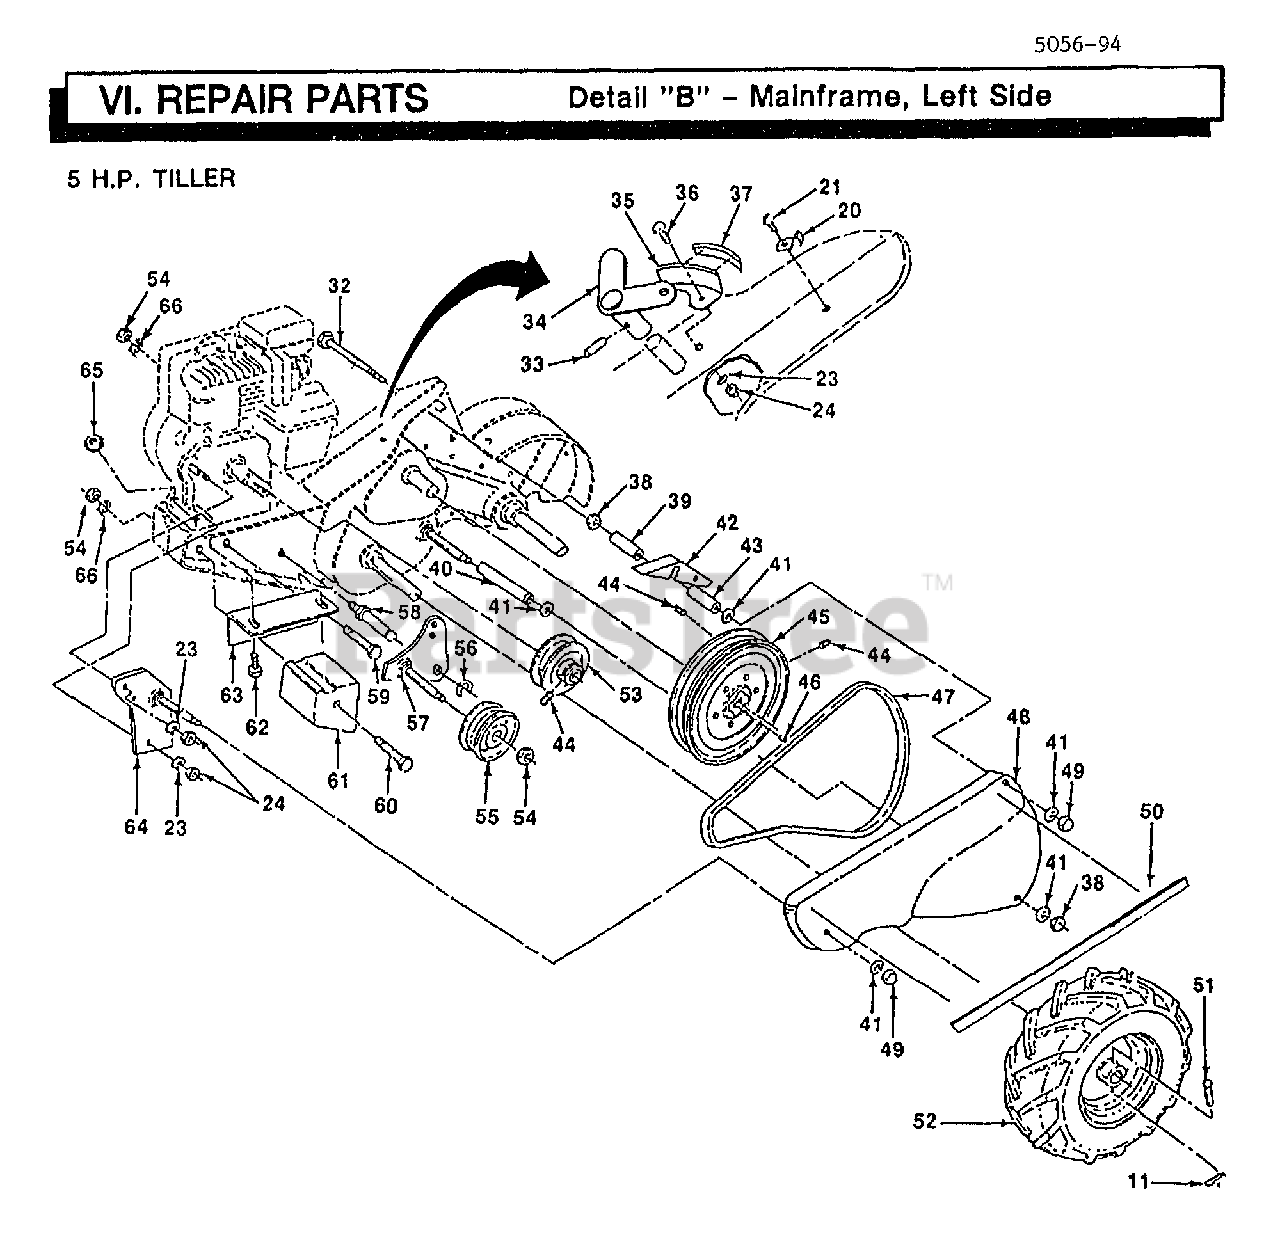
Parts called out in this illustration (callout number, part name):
11	RETAINER M
23	LOCKWASHER
32	BOLT-HEX TI
34	LEVER ASM CRT
35	PANEL TI
36	BOLT
38	NUT.HEX.5/16-18
39	SPACER CRT
40	SPACER
41	WASHER
42	GUARD CRT
43	SPACER CRT
44	SET SCREW
45	"SHEAVE 10"" CRT"
46	KEY T
49	NUT TI
50	DECAL BELT GUARD
52A	TIRE.CHV.13X5.0-6
54	NUT.HEX.3/8-16UNC
55	PULLEY-IDLER TI
56	KLIP RING
58	SHIFT ARM CRT
59	BOLT
60	BOLT CRT
61	COUNTERWEIGHT CRT
62	BOLT.HEX.5/16-1.5
63	BRACKET LH CRT
64	BRACKET ASSY CRT
66	LOCKWASHER
